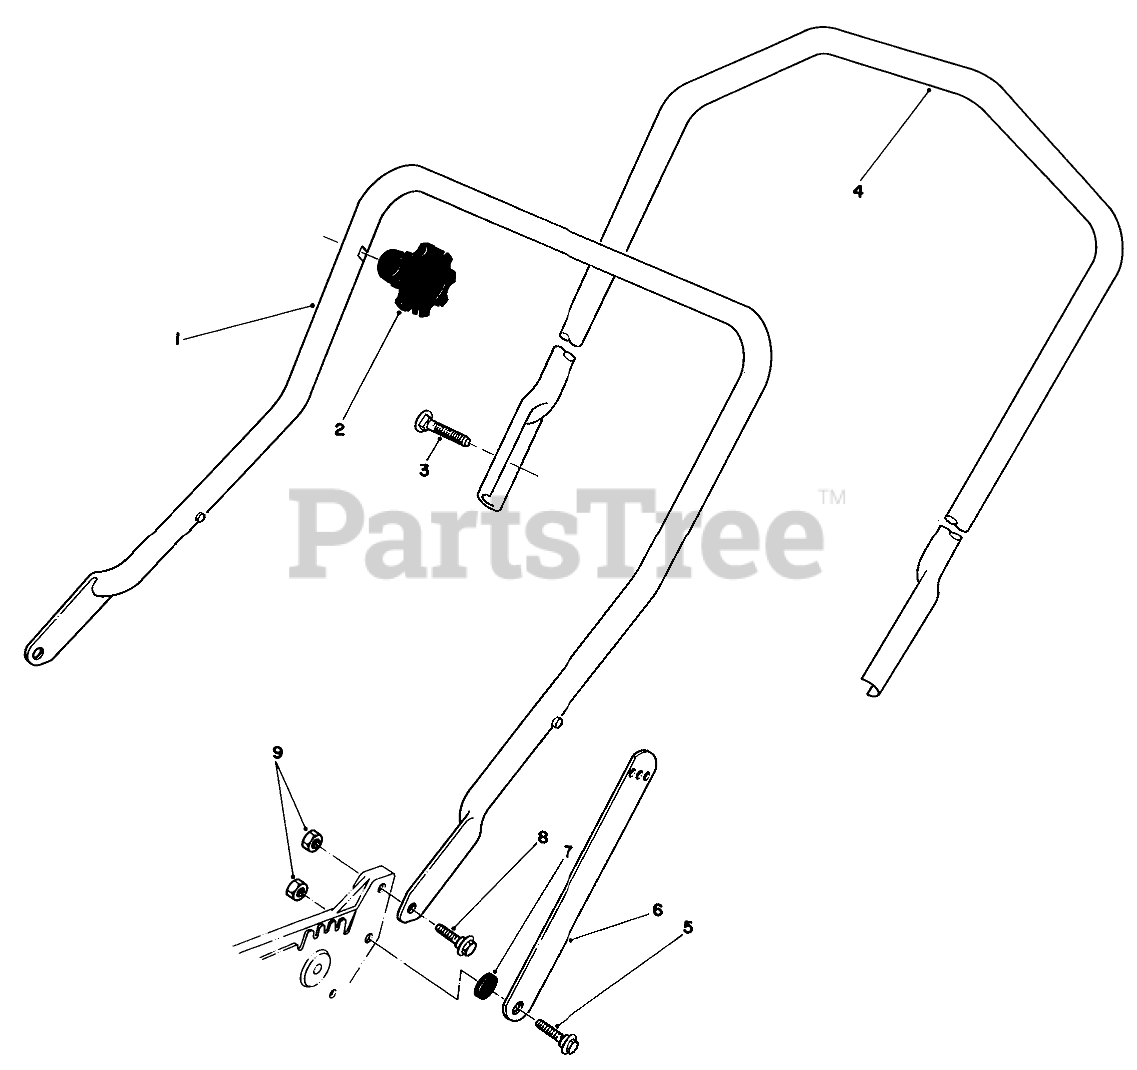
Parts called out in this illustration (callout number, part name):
1	Handle-Lower
3	5/16-18 X 2 HNDLE SCREW
4	UPPER HANDLE
5	SCREW-SHOULDER
6	Handle Latch
7	SPACER
8	SCREW-SHOULDER
9	NUT-LOCK, NI
